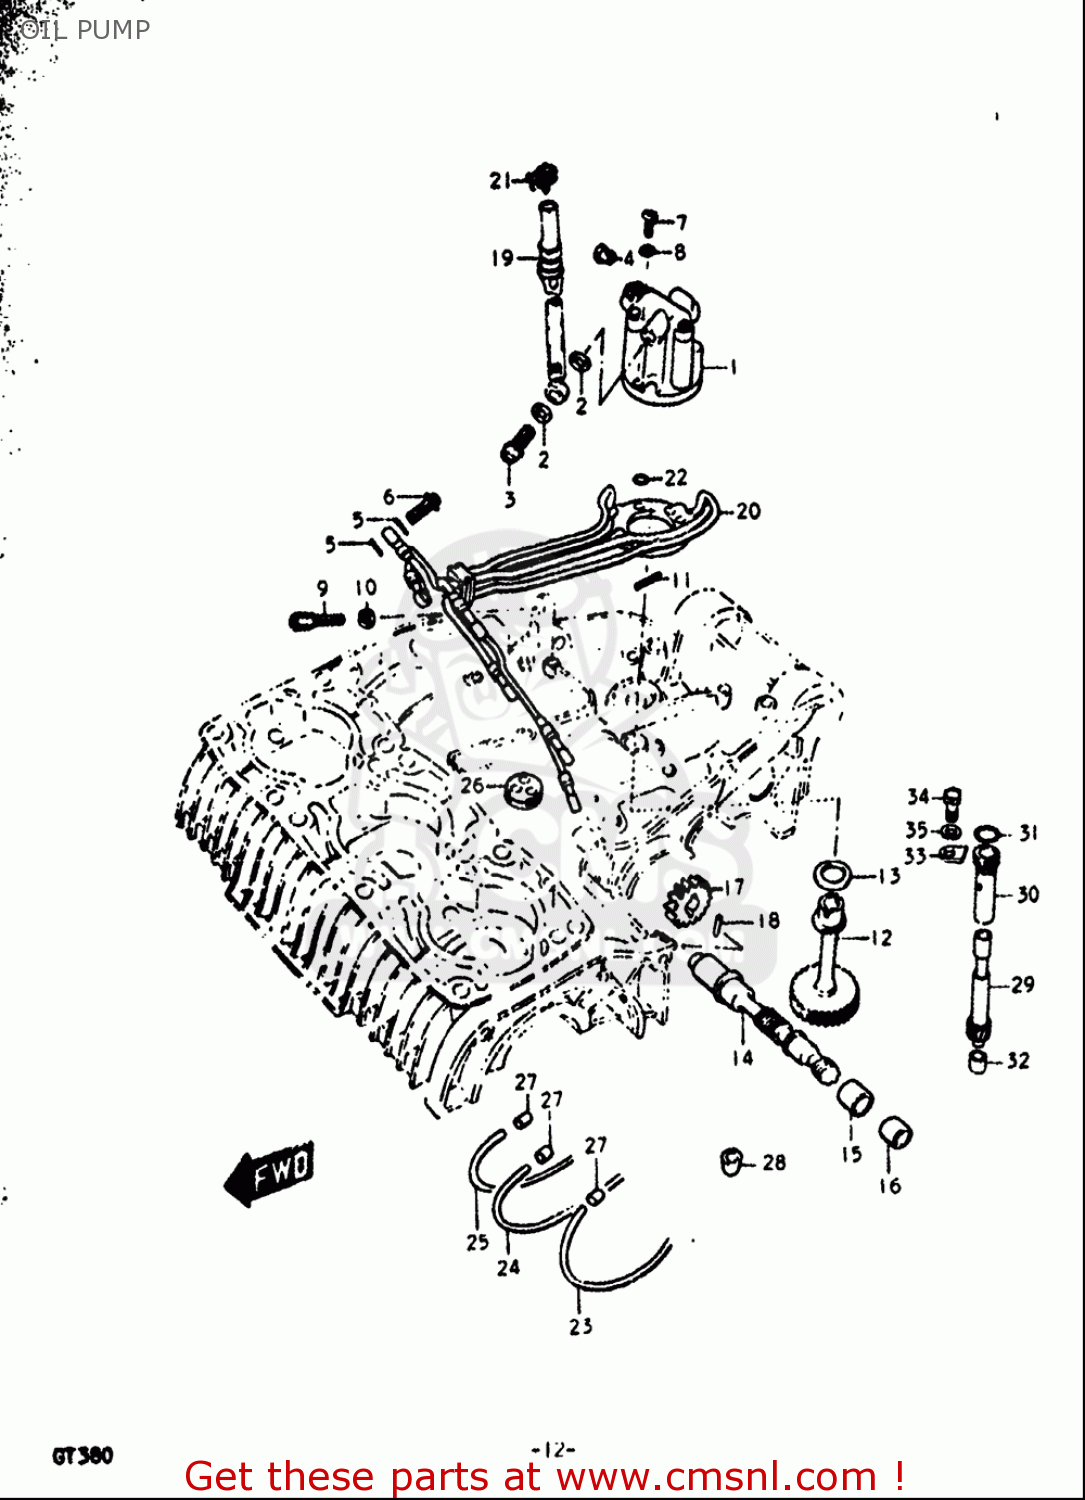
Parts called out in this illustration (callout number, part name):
2	GASKET(6.2X11X1).2 (NAS)
3	UNION BOLT
4	TERMINAL,CABLE
5	GASKET(6.2X11X1).2 (NAS)
6	UNION BOLT
7	SCREW
8	WASHER,LOCK
9	BOLT
10	NUT
11	PIN(3X13.8)
13	SHIM(14X22X1)
18	PIN(3X13.8)
21	CLAMP
22	O RING(D:1.9,ID:3.8)
23	HOSE(2X5X600)
24	HOSE(2X5X600)
25	HOSE(2X5X600)
27	CLIP
31	O RING(D:1.3,ID:9.6)
33	PLATE,TACH DRIVE GEAR SLEEVE
34	BOLT
35	WASHER,LOCK
